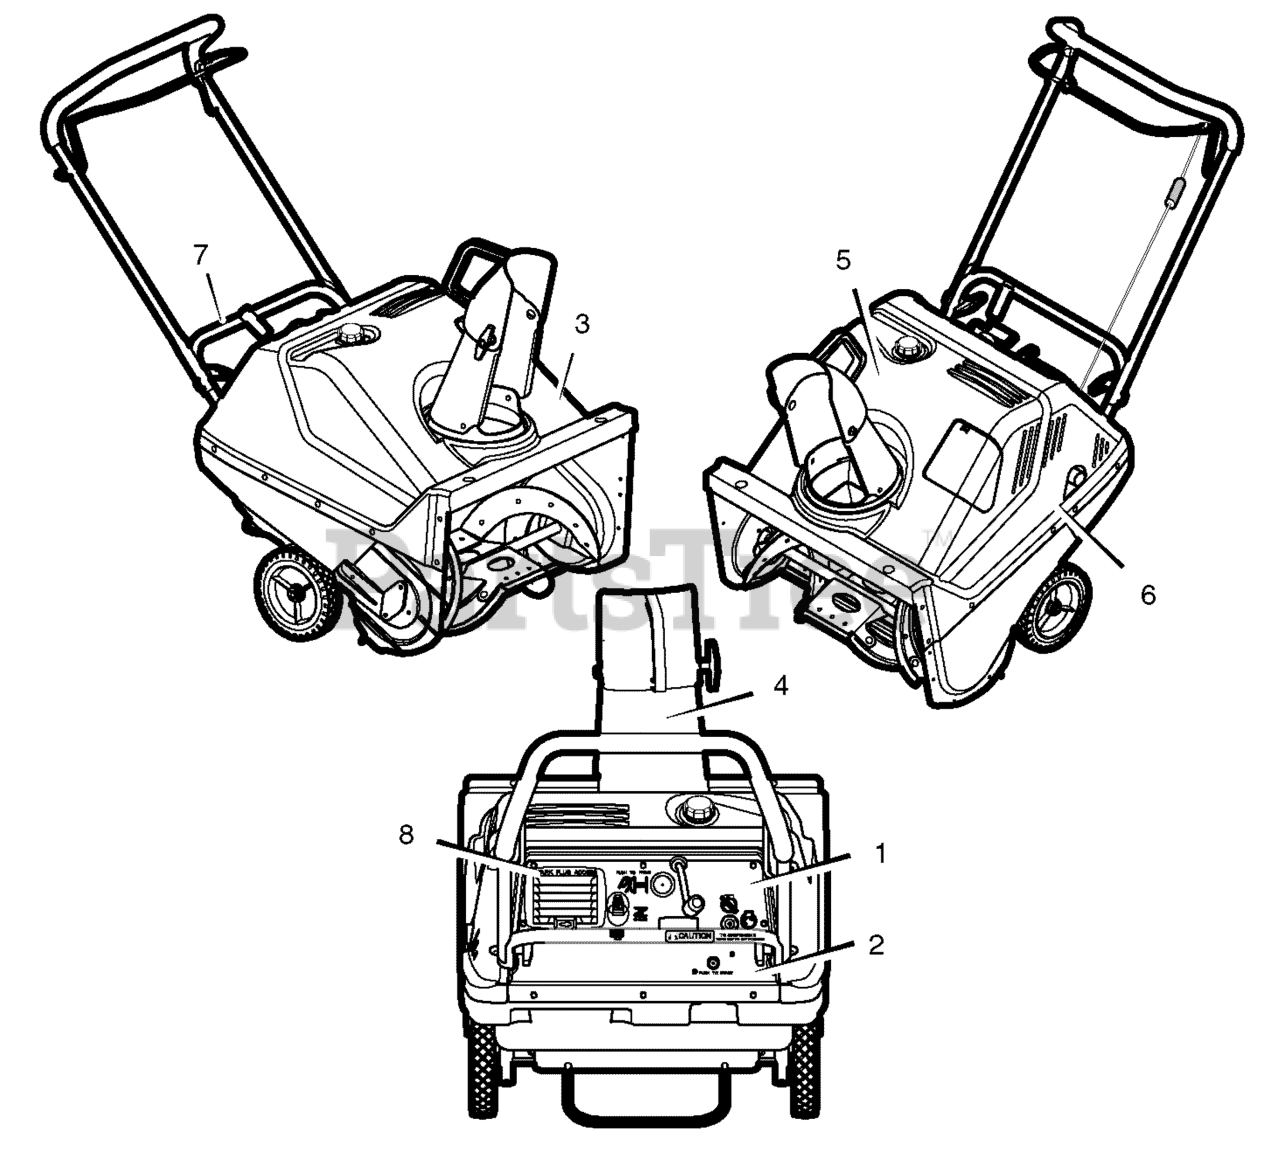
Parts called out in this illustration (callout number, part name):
1	Decal, Panel 22" ES SEARS
2	Decal, Electric Start
3	Decal, Auger Danger
4	Decal, Danger Chute Hand
5	Decal, 5HP/22" CRAFTSMAN
6	Decal, Danger Muffler
7	Decal, Auger Control
8	Decal, Spark Plug Access 22"
